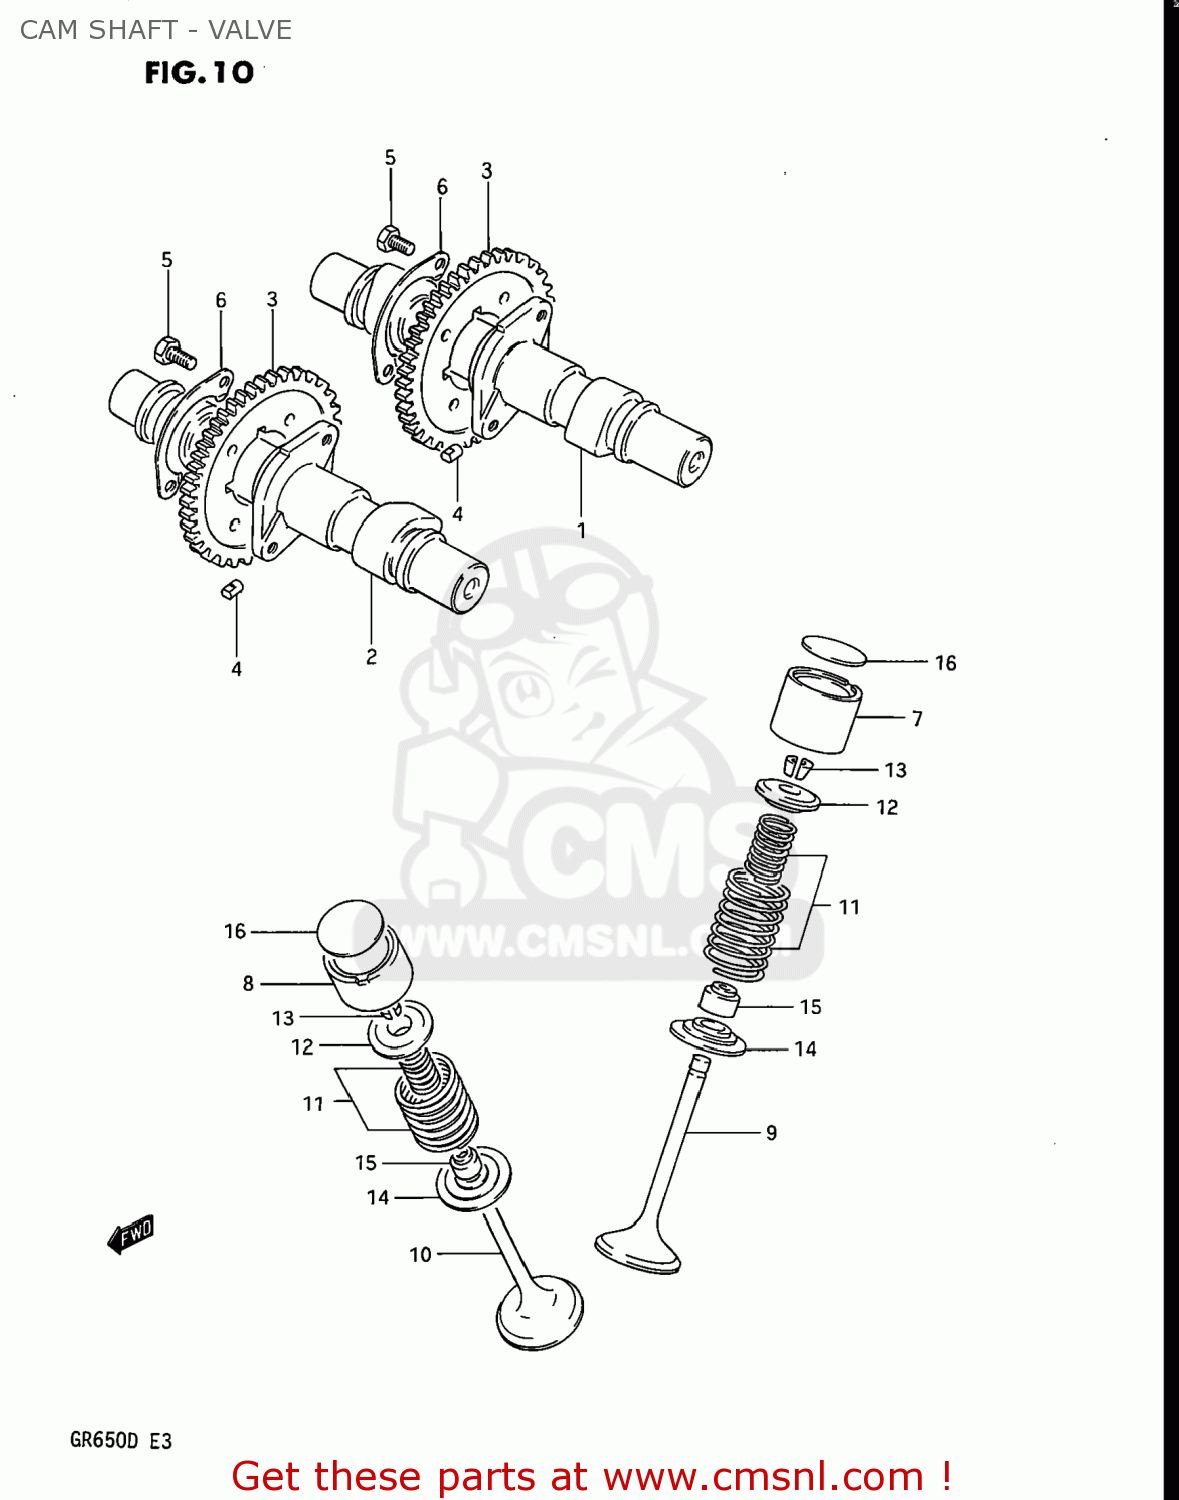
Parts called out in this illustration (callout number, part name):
1	CAMSHAFT,INTAKE
2	CAMSHAFT,EXHAUST
3	SPROCKET,INTAKE CAMSHAFT
4	PIN,SPROCKET
5	BOLT(6X12.5)
6	WASHER,CAM CHAIN SPROCKET
7	TAPPET,INTAKE
8	TAPPET
9	VALVE,INTAKE
10	VALVE,EXHAUST
11	SPRING SET,VALVE
12	RETAINER,VALVE SPRING
13	COTTER VALVE
14	SEAT,VALVE SPRING
15	SEAL,OIL(7X14.4X9)
16	SHIM,TAPPET
17	SHIM SET,TAPPET
18	CASE
